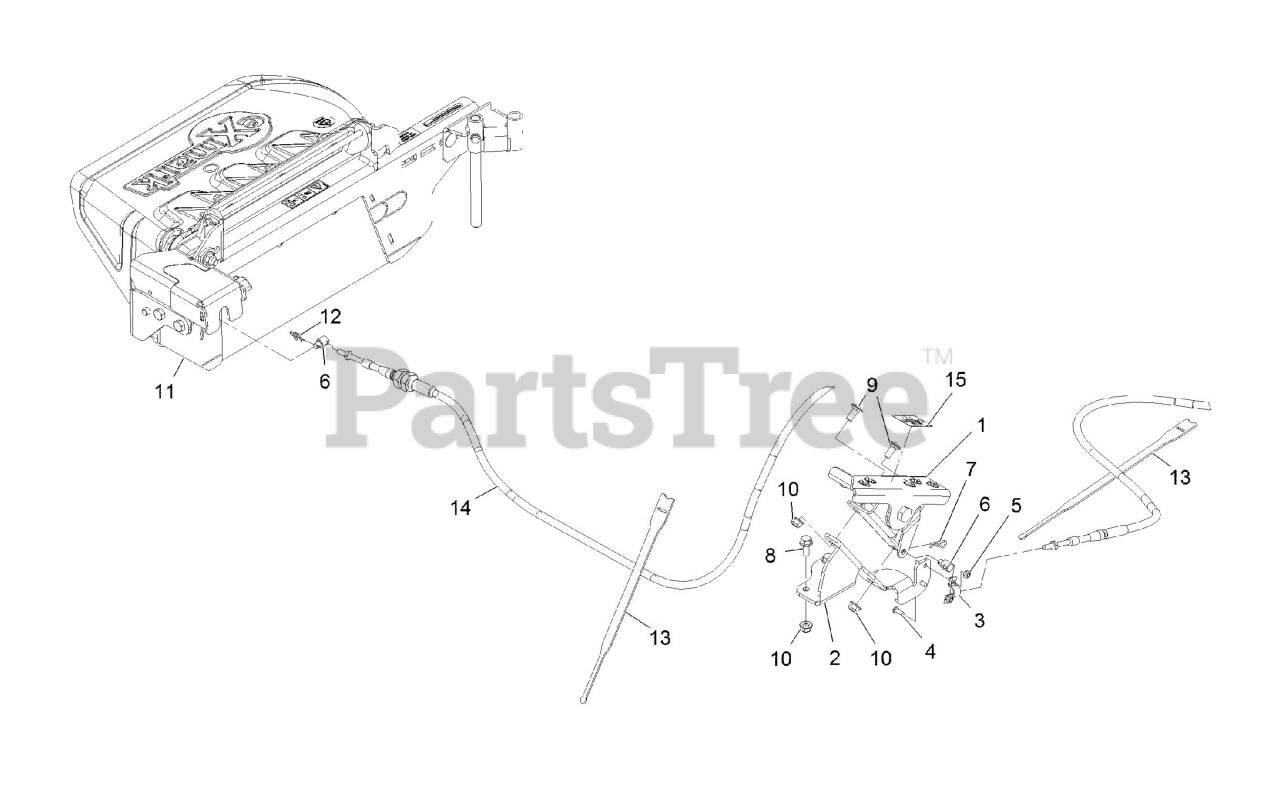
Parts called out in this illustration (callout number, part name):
1	ASM, PEDAL, OCD GATE
2	MOUNT-PEDAL, OCD
4	SCREW-PPH
5	NUT-LOCK, NI
6	PIVOT, CONTROL CABLE
7	PIN-COTTER
8	SCREW-HHF
9	SCREW-CARR
10	NUT-HF, NI
11	ASM, OCD
12	PIN-COTTER, LOCKING
13	STRAP-VELCRO, CABLE TIE
14	CABLE-DISCHARGE GATE
15	DECAL-OCD OPERATION
